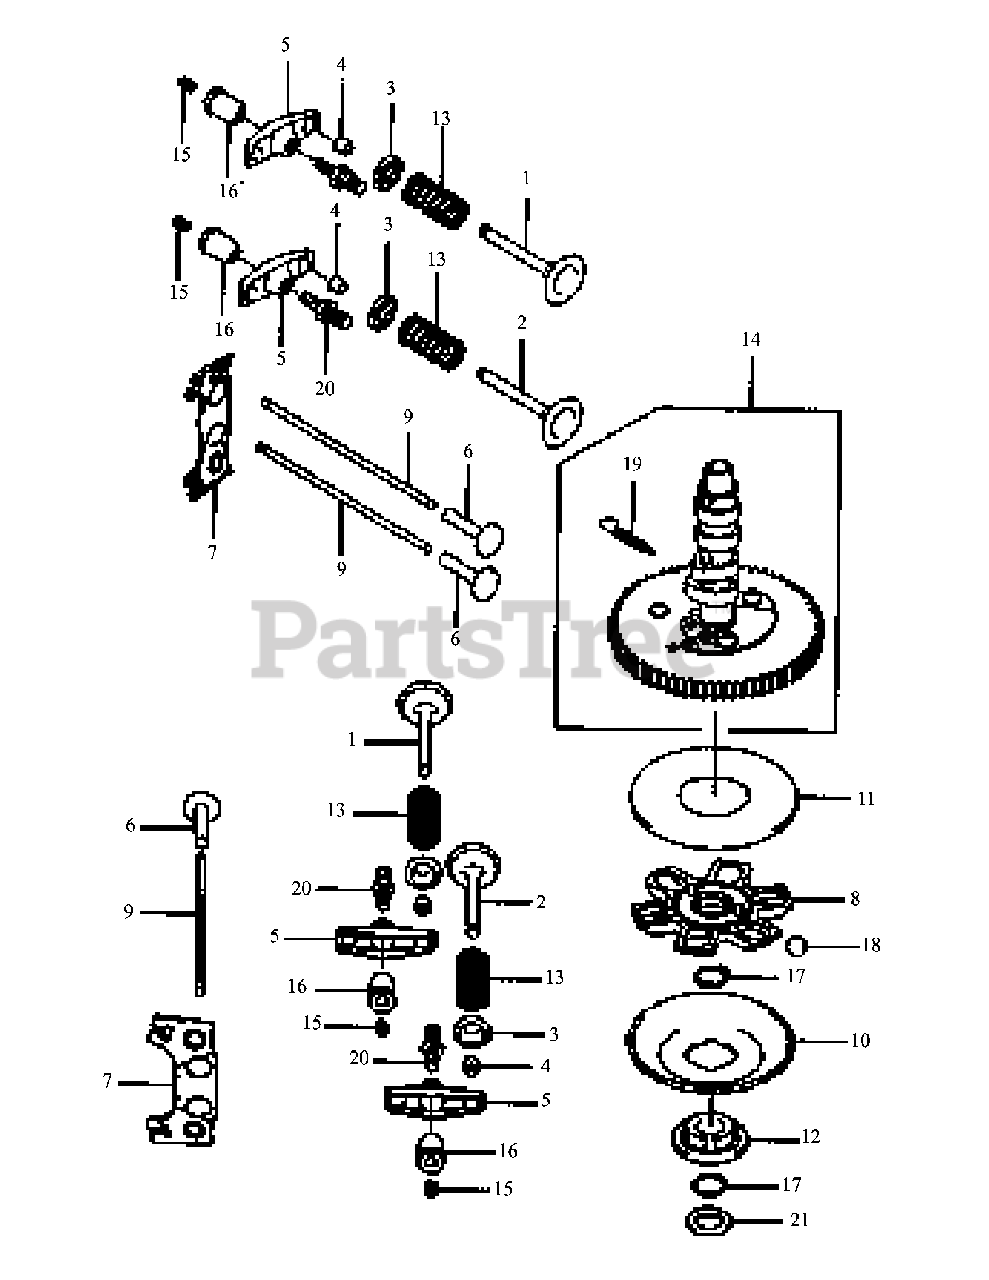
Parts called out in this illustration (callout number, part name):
2	Valve-Exhaust
3	Retainer, Valve Spring
7	Guide, Push Rod
13	Spring-engine Valve
14	Camshaft-Complete
17	Ring-Snap
18	Ball
19	Spring
